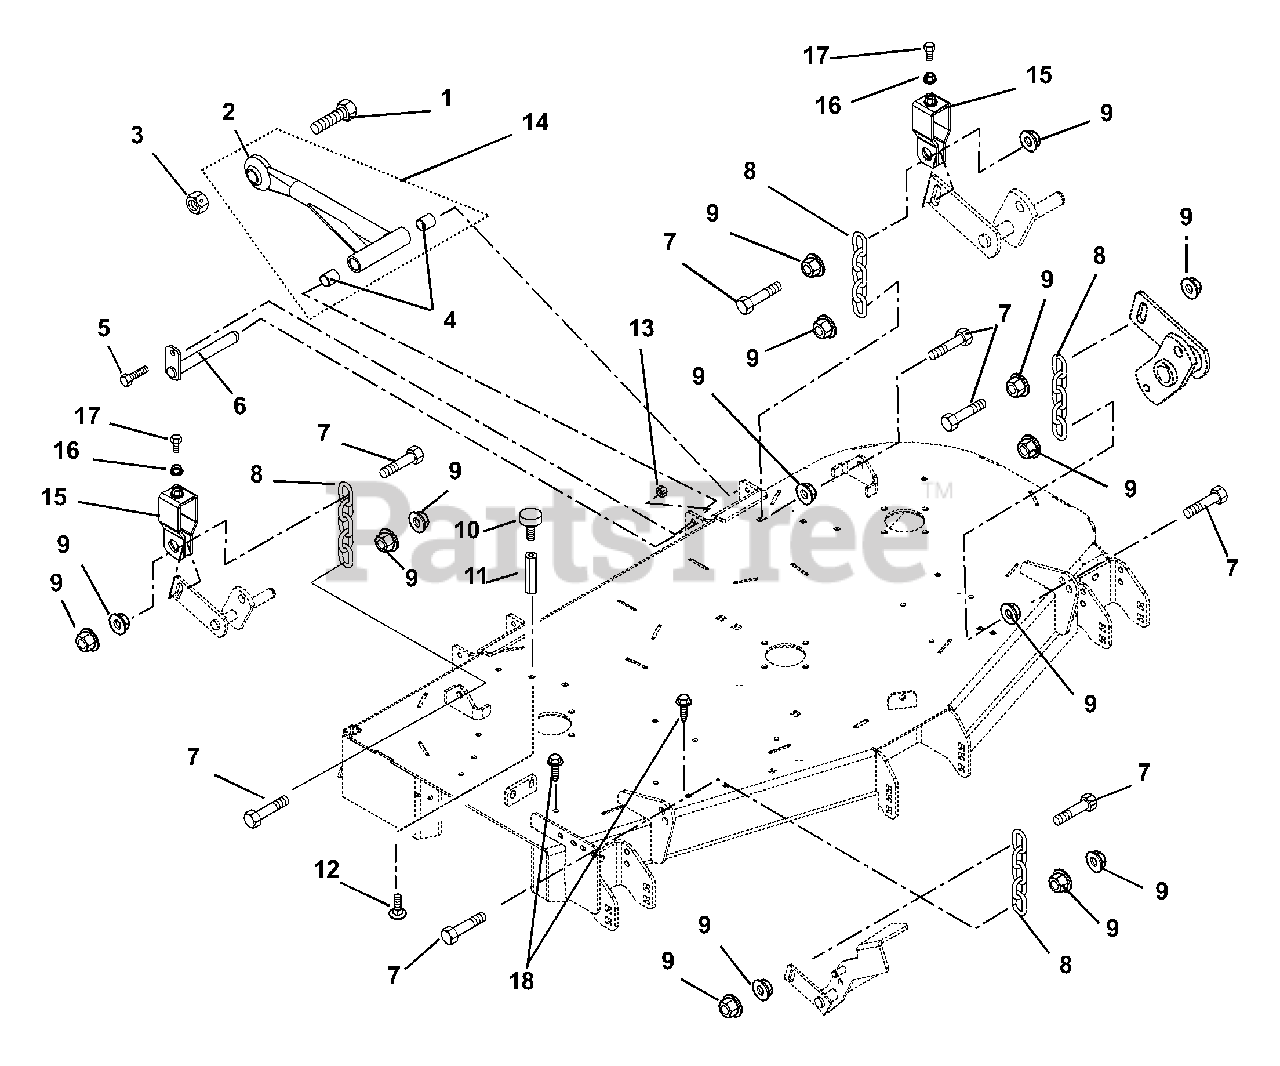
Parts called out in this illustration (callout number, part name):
1	Bolt, Hex .875-9 x 2.75 Grade 5
2	Mower Mounting Arm Weldment
3	Nut, Locking-Center .875-9
4	Bearing, .75 x .875 x 1.00
5	Bolt, Hex .38-16 x .75 Grade 5
6	Weldment, Mower Mounting Pin
7	Bolt, Hex M12-1.75 x 50 Grade 5
8	Chain, Link
9	Nut, Spin Lock-Flange M12-1.75
10	Bumper, Rubber
11	Nut, Coupling .31-18 x 3.00
12	Bolt, Round Head Square Neck .31-18 x .75
13	Nut, .38-16 Nyloc Flange
14	Assembly, Mower Mounting Arm
15	Bracket, Deck Leveling
16	Nut-Jam .312-18
17	Bolt, Hex .31-18 x 1.75 Full Thread
18	Screw, Tapping .38-16 x .50 Hex Washer Head Thread
18	Screw-Tapping .38-16 x .50 Hex Washer Head Thread
